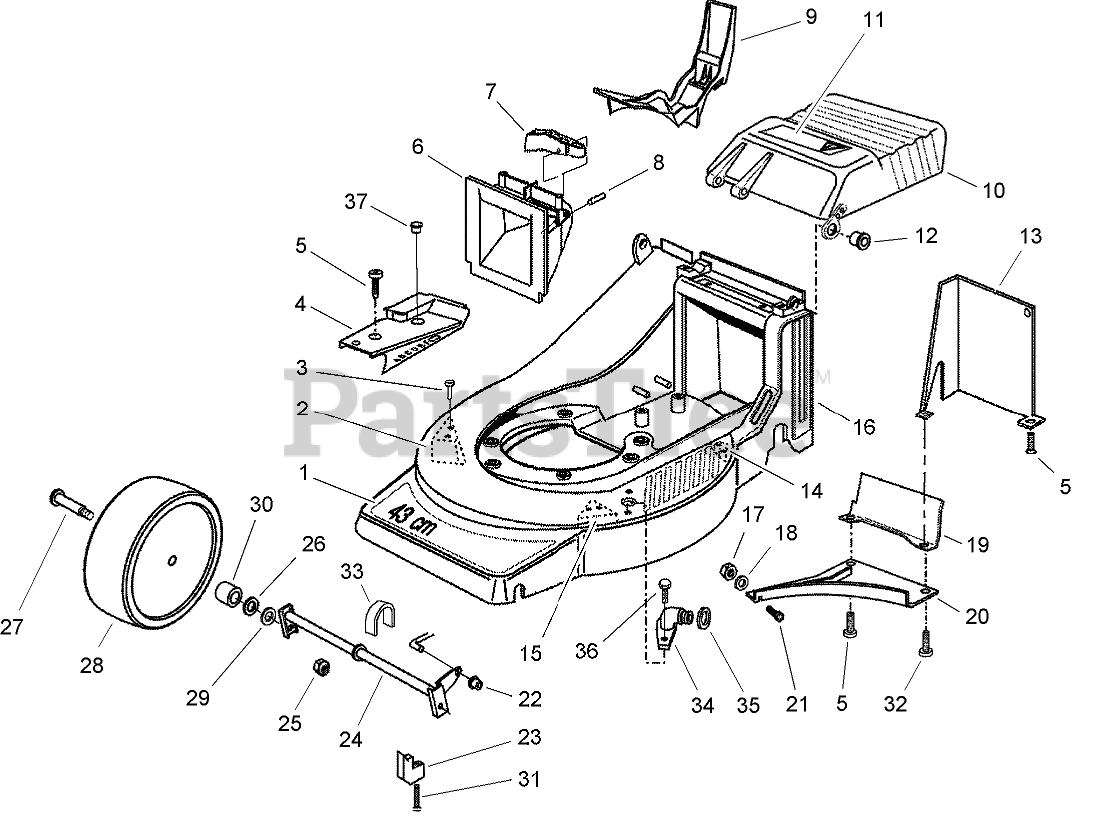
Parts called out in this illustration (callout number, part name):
1	DECAL
2	KICKER
3	SCREW-PPH
4	Cover-Belt
5	SCREW
6	GRIP-LOWER
7	TRIGGER-HEIGHT OF CUT
8	PIN-SPIRAL
10	DISCHARGE DOOR ASM
11	DECAL-DANGER
12	BUSHING-DOOR
13	COVER-SHIELD
14	KICKER
15	KICKER
16	HOUSING
17	NUT-LOCK, NI
18	WASHER-FLAT
19	BAFFLE-BAGGER, REAR
20	BAFFLE
21	SCREW-PPH
22	NUT-PUSH
23	RETAINER-AXLE
24	AXLE-FRONT
25	Nut-Lock
26	WASHER
27	Bolt-Wheel
28	WHEEL-FRONT
29	WASHER-SPRING
30	BUSHING
31	SCREW-RETAINER
32	SCREW-BAFFLE
33	CAP-AXLE, FRONT
34	FITTING-WASHOUT
35	O-RING
36	SCREW-HWH
37	Cap-Cover
